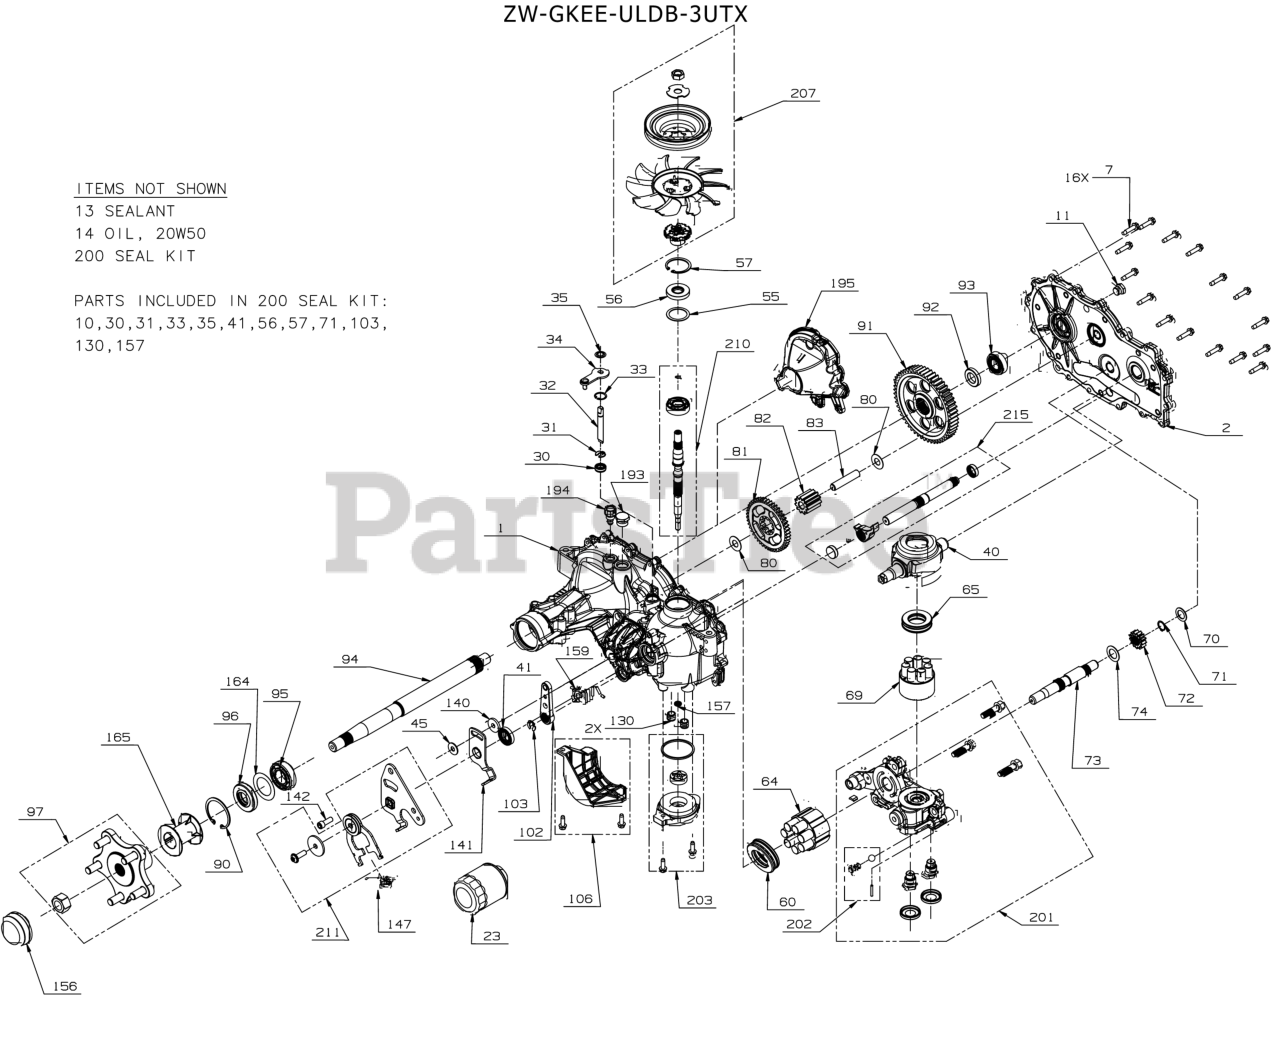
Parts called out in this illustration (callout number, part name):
1	MAIN HOUSING KIT (RH)
2	SIDE COVER KIT (RH)
7	SCREW-WASHER HEAD
11	VENT PLUG
13	SEALANT-HOUSING
23	OIL FILTER
30	SEAL-LIP .375 X .75 X .25
31	RETAINING RING
32	BYPASS RODS
33	RETAINING RING
34	ARM-BYPASS
35	RETAINING RING
40	SWASHPLATE-TRUNNION
41	LIP SEAL
45	FLAT WASHER
55	WASHER 1.23X1.56X
56	LIP SEAL
57	RETAINING RING
60	THRUST BEARING
64	CYLINDER BLOCK ASSEMBLY
65	THRUST BEARING
69	BLOCK KIT-CYLINDER
70	FLAT WASHER
71	RETAINING RING
72	GEAR - 13 TOOTH STEEL
73	MOTOR SHAFT
74	MOTOR SHAFT WASHER
80	WASHER
81	GEAR - 46 TOOTH
82	GEAR-11 T
83	PIN-JACKSHAFT
90	RETAINING RING
91	GEAR - 54 TOOTH
92	SPACER .75X1.32X.257
93	BALL BEARING
94	AXLE SHAFT
95	BALL BEARING
96	OIL SEAL
97	5 BOLT HUB KIT
102	BRAKE LEVER
103	RETAINING RING
106	FILTER GUARD KIT
130	TUBE-CHARGE TRIPLE O-RING
140	SPACER .32 x 1.005 x .179
141	ARM-NEUTRAL (RH)
142	SCREWS KIT-RTN
147	EXTENSION SPRING
156	COVER-NUT
157	KIT-GEROTOR SEAL
159	TORSION SPRING CCW
164	SPACER
165	TUBE-AXLE 2.03
193	PLUG 3/4-16
194	BREATHER
195	EXPANSION TANK (RH)
200	SEAL KIT
201	CENTER SECTION KIT (RH)
202	KIT-CHARGE RELIEF
203	CHARGE KIT
207	FAN & PULLEY KIT
209	PULLER KIT-HUB
210	INPUT SHAFT KIT
211	RETURN KIT-NEUTRAL (RH) ZT2800 RZT
215	OUTPUT SHAFT KIT
